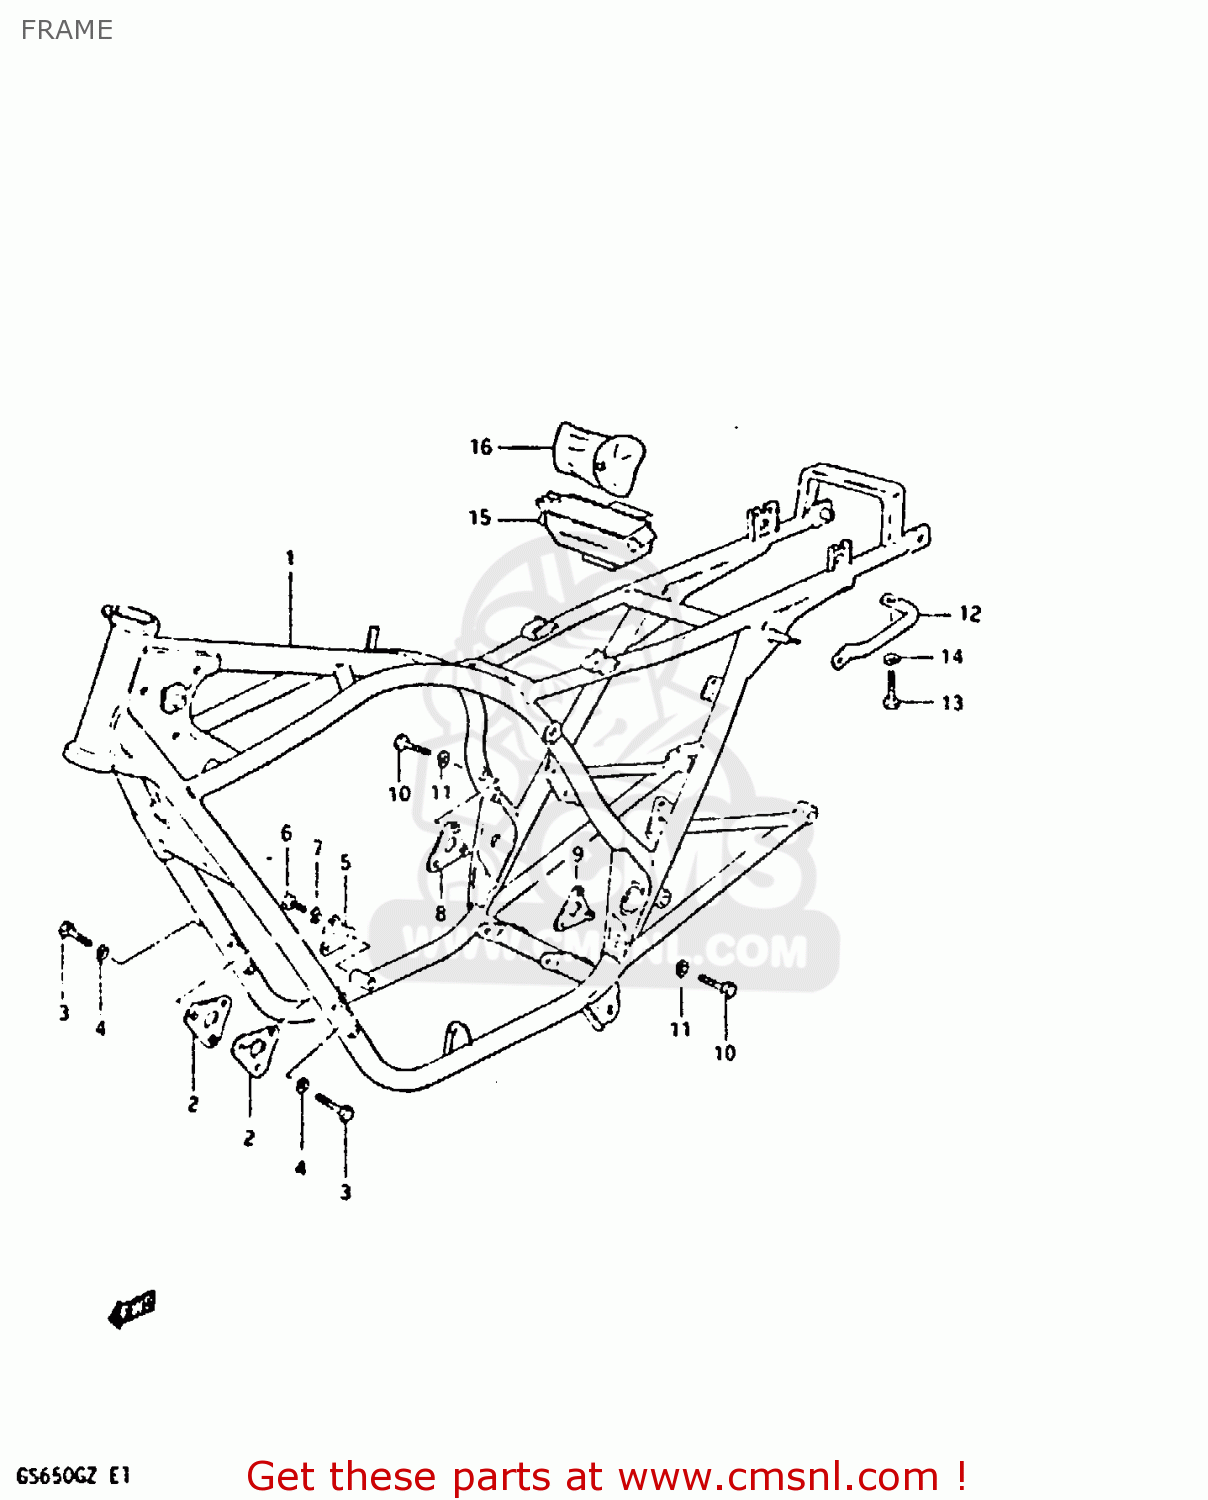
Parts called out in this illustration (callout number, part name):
1	FRAME (BLACK)
2	PLATE COMP,ENGINE MOUNTING
3	BOLT
4	LOCK WASHER
5	BOLT,CRANKCASE ADJUST
6	BOLT
7	LOCK WASHER
8	PLATE,ENGINE MOUNTING NO
9	PLATE,ENGINE MOUNTING
10	BOLT
11	LOCK WASHER
12	GRIP,FRAME HANDLE
13	BOLT
14	WASHER
15	HOLDER,TOOL
16	TOOL SET
